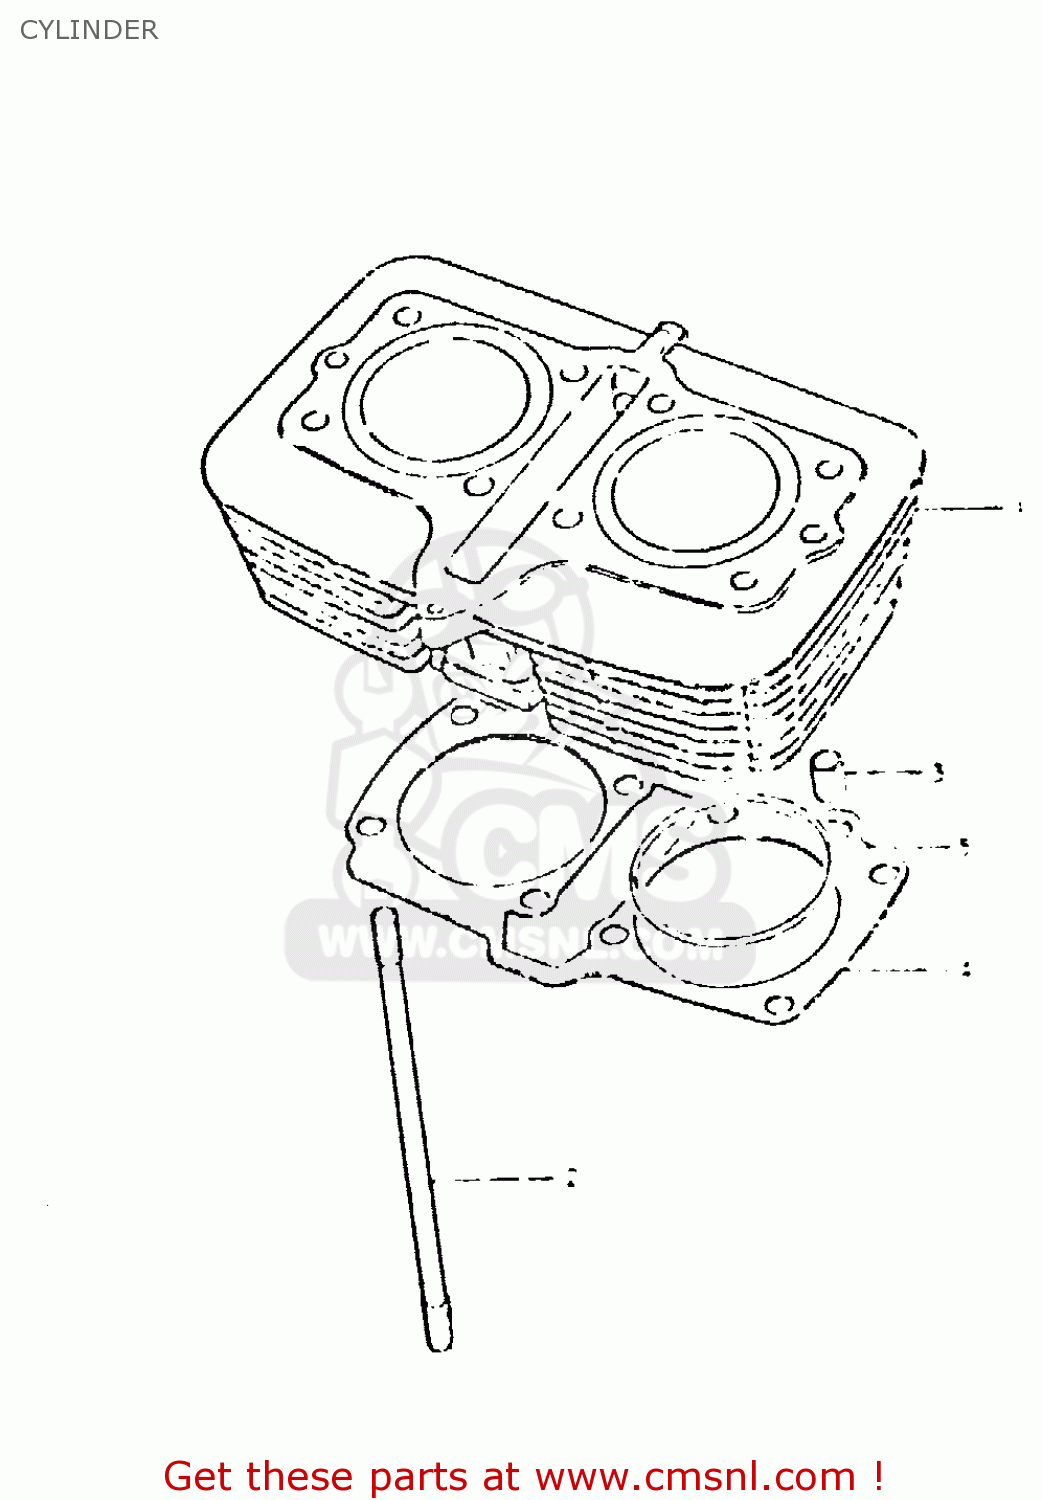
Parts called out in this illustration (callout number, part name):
1	CYLINDER
2	STUD
3	PIN
4	GASKET,CYLINDER (MCA)
5	O RING(D:2,ID:70)
